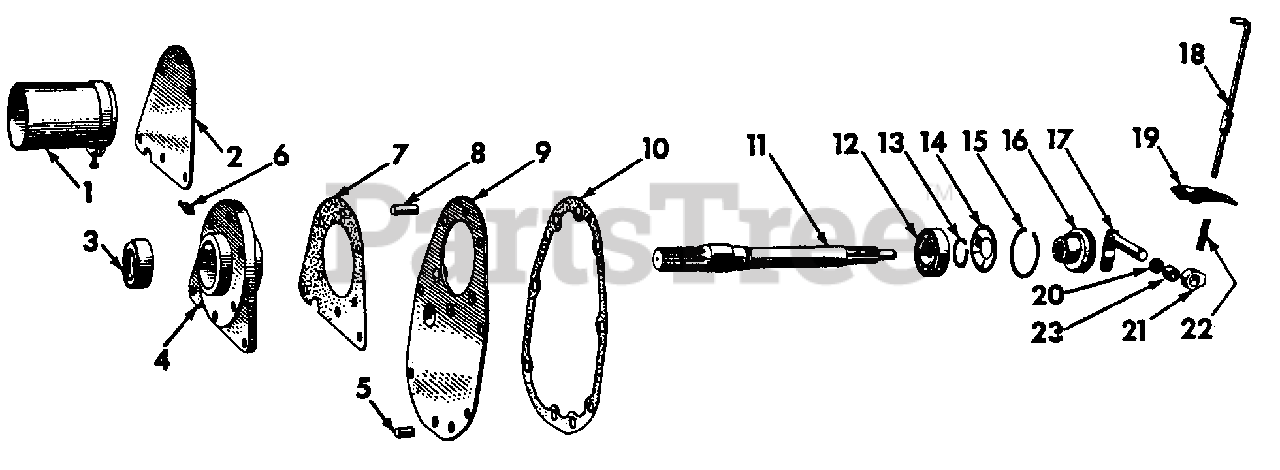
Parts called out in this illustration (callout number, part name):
1	Guard Assy, PTO Shaft
2	Cover, Transmission Case Rear Cover Opening
3	Seal, PTO Shaft Oil
4	Retainer Assy, PTO Shaft Oil Seal & Brg
5	Pin, Cover Lower Dowel
6	Fitting, 3/16 X 65 Deg Drive Type Lube
7	Gasket, Rear Cover Opening
8	Pin, Cover Upper Dowel
9	Plate Assy, Transmission Rear Cover
10	Gasket, Rear Cover
12	Bearing, PTO Shaft Ball
13	Ring, PTO Shaft Brg Snap
15	Ring, PTO Shaft Brg Snap
16	Clutch, PTO Shifter
17	Lever Assy, PTO Shifter
18	Rod Assy, PTO Shifter
19	Guide, PTO Shifter Rod
20	Seal, PTO Shifter Shaft
21	Bushing, PTO Shifter Lever
22	Spring, PTO Shifter Rod
23	Spacer, PTO Shifter Lever
